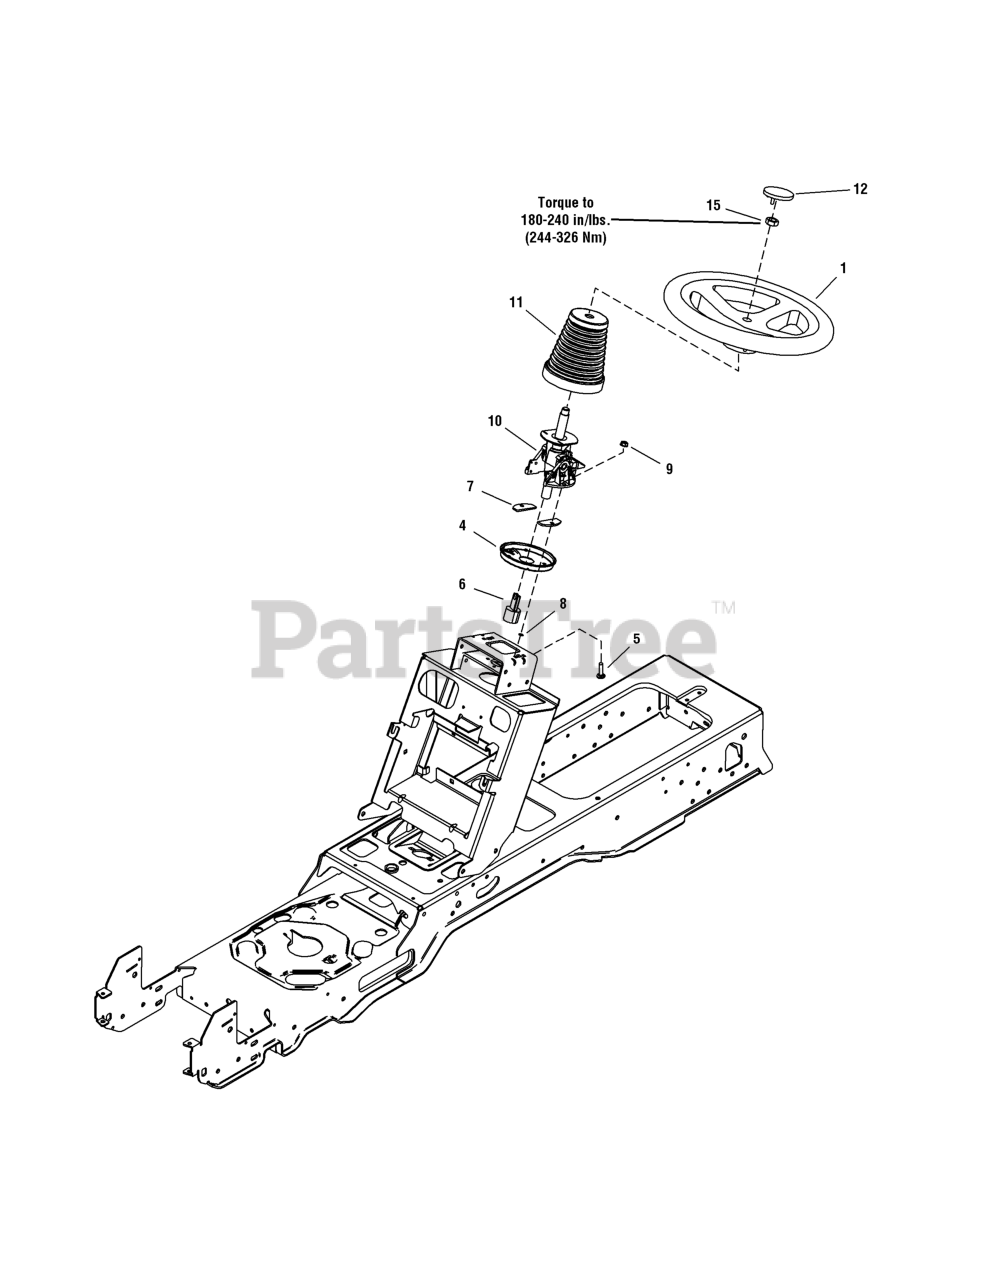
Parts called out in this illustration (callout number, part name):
1	STEERING WHEEL
4	PLATE, Steering Mounting
5	BOLT, Carriage, 5/16-18 x 1-1/4, G5
7	SPACER, Flat
8	NUT, Push Pal
9	NUT, Hex Keps 5/16-18
10	STEERING UNIT, Tilt
11	BELLOWS, Tilt Steering Unit w/Slot
12	CAP, Steering Wheel
15	NUT, Hex Lock, ESNA Light, 5/8-18
